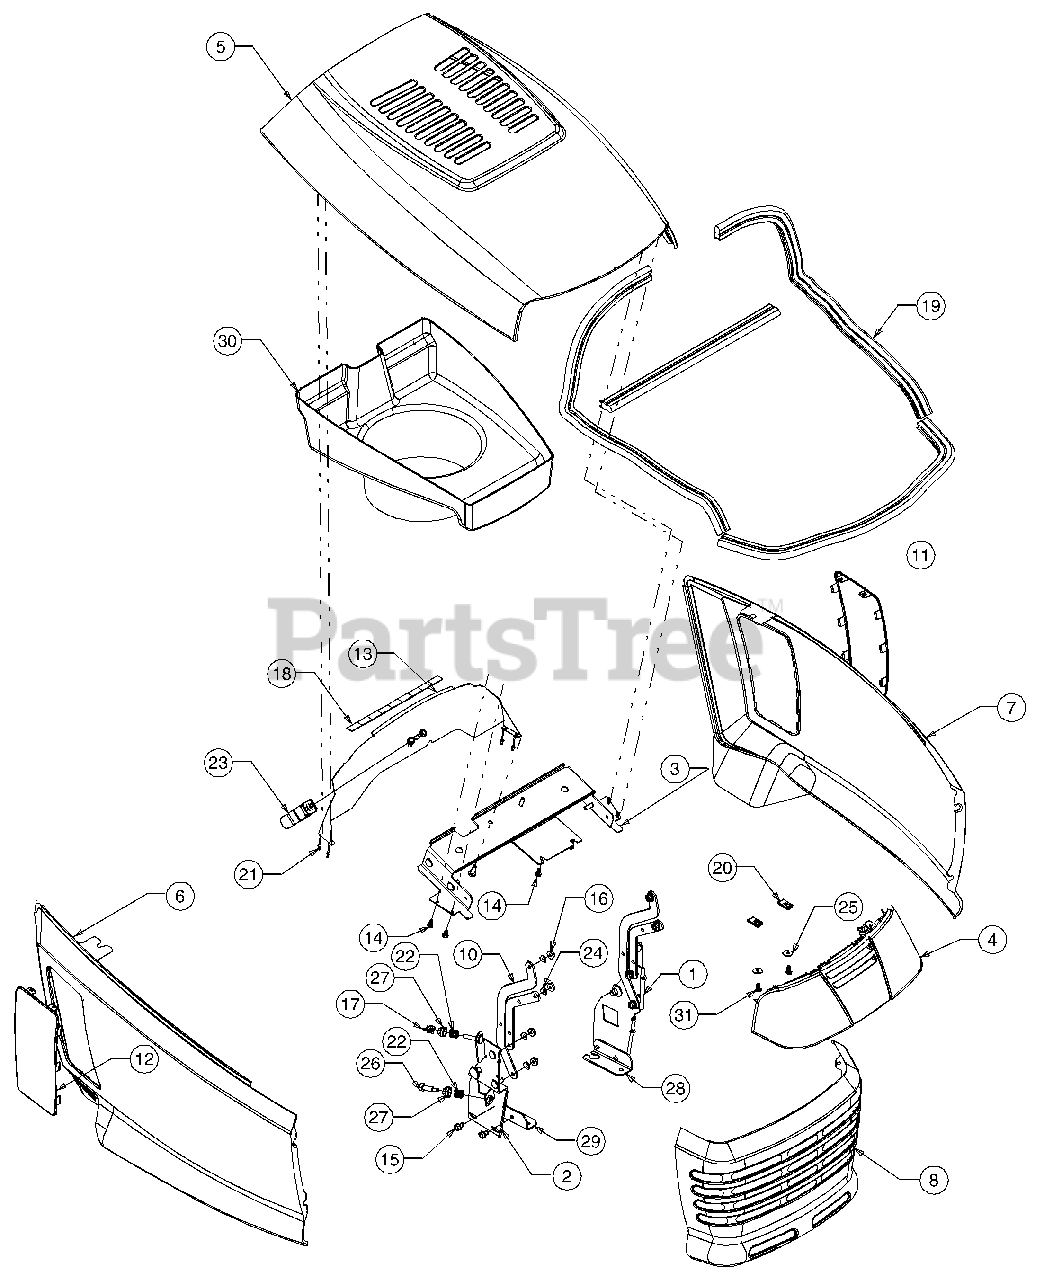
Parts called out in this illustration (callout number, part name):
1	Bracket Assembly, Grille LH
2	Bracket Assembly, Grille RH
3	Bracket Assembly, Hood
4	Headlight Assembly, Front
10	Link, Hood, Rear
14	Screw, #10-16, 0.500, Pan Phillips
15	Screw, Self-tapping, 1/4-20, 0.500
16	Nut, Flange Lock, 1/4-20
17	Nut, Wing, 1/4-20
18	Tape, Two-sided Adhesive Foam
19	Seal, Heat Baffle
20	Nut, Speed, 10z U-type
21	Rivet, Pop, .125 OD, #42
22	Spring, Compression, .50 OD x .5 Lg
23	Spring, Latch, Hood
24	Washer, Spring, .265 x.562 x.025
25	Washer, Flat, .194 x .62 OD x .063
26	Screw, Shoulder, .31 x .75, 1/4-20
27	Bushing, Tapered, .32 ID x .69 OD
31	Hex Screw, #10-16 x 0.625
